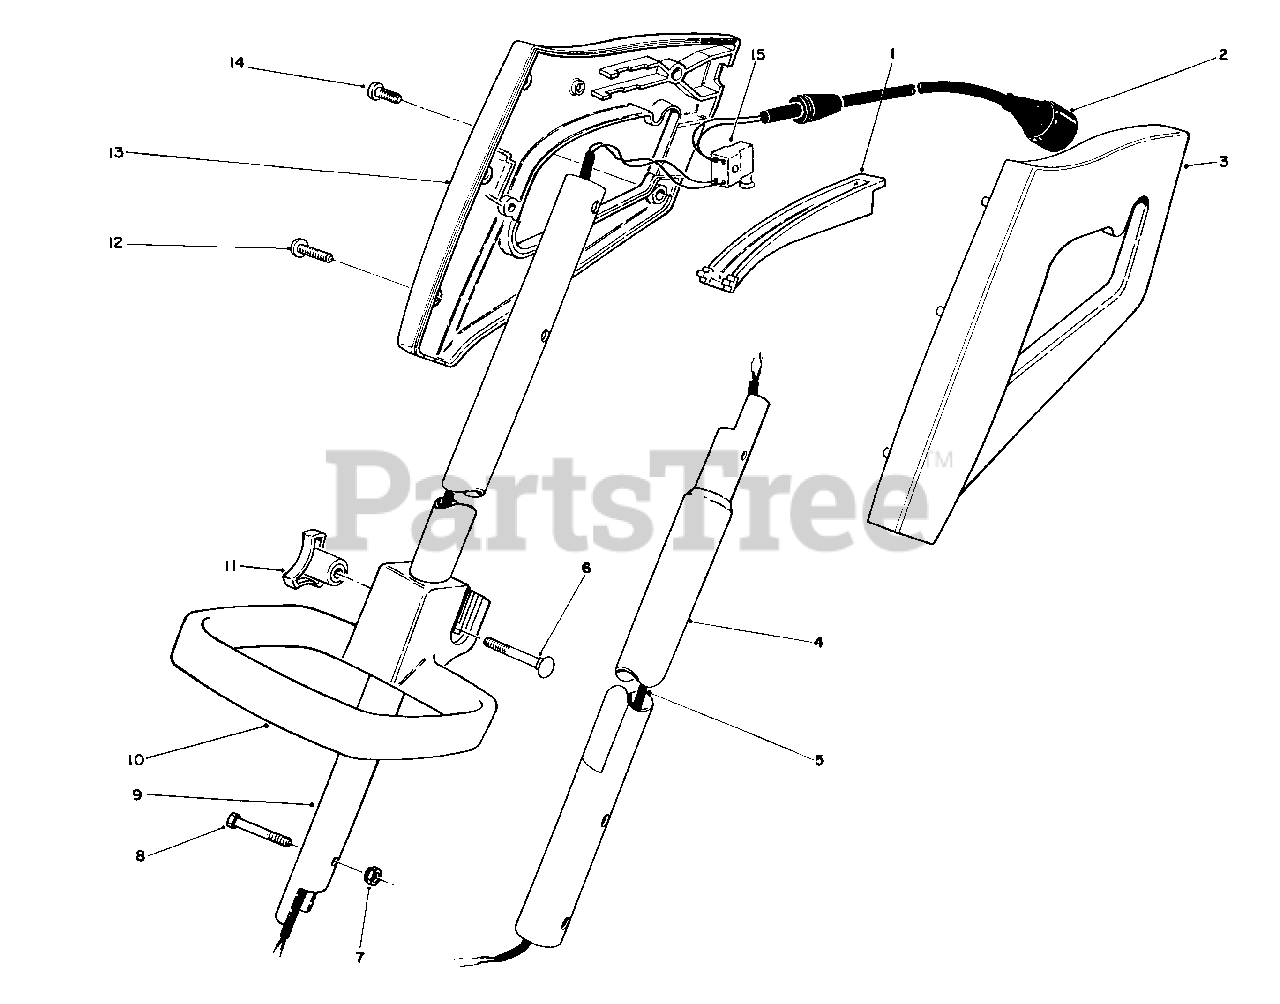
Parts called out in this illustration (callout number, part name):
1	Bar-Switch
2	Cord-Power
3	Grip-Left Handle
4	Tube-Lower
5	Wiring Harness
6	Bolt-Carriage
7	Nut-Lock
8	Screw-Machine
9	Tube-Upper
10	Handle-Adjustable
12	Screw
13	Grip-Right Handle
14	Screw-Thread Forming
15	Switch-Single Speed
